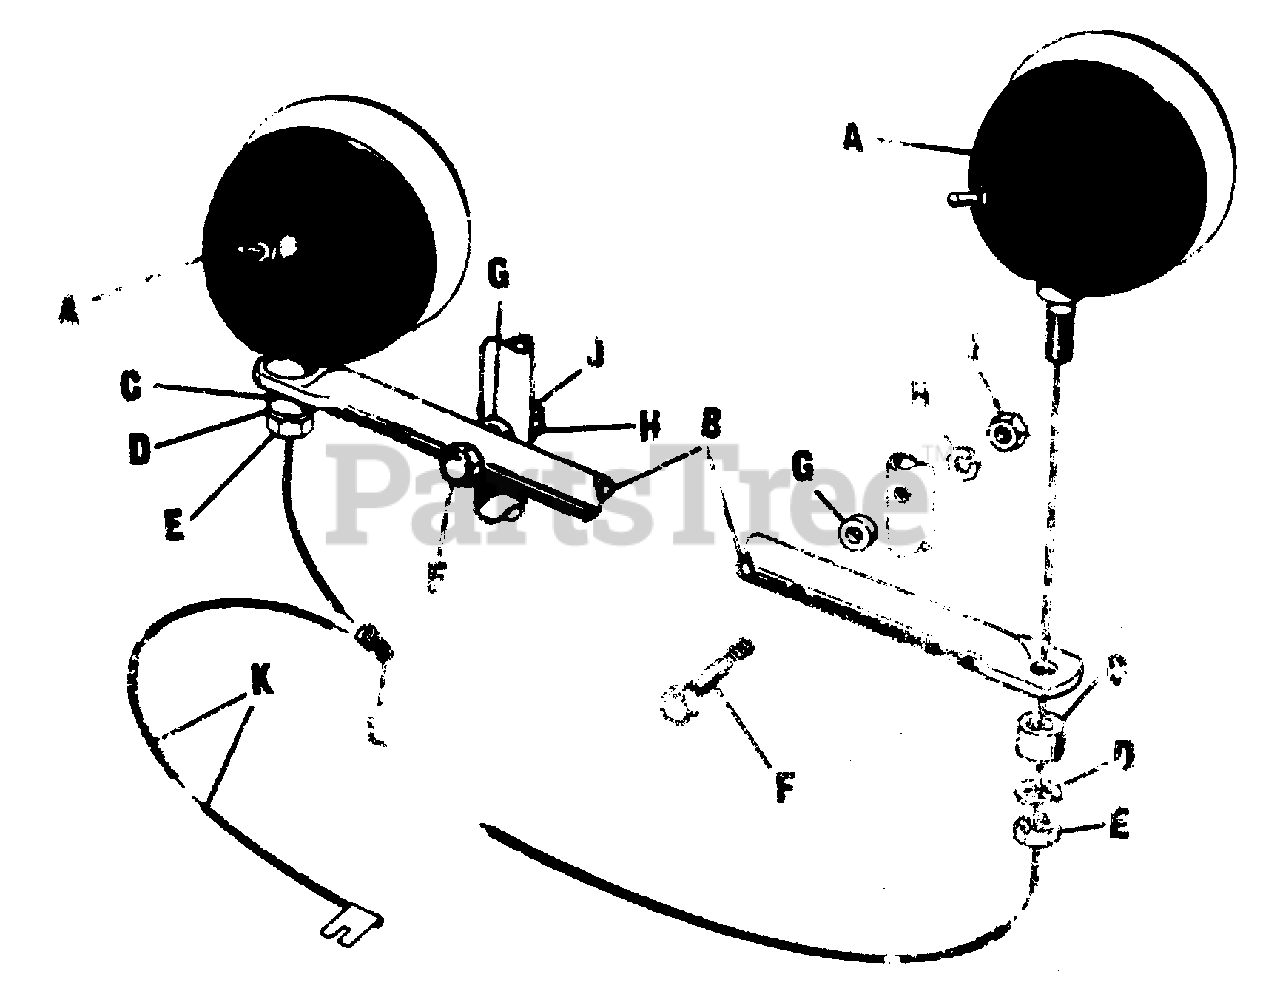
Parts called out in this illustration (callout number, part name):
A	Lamp Assembly
B	Supports, Lights
D	Lock Washer, 1/2"
E	Hex Nut Full, 1/2"-13
F	Hex Capscrew, 5/16"-18 x 2-1/2"
H	Lock Washer, 5/16"
J	Hex Nut, Full, 5/16"-18
K	Wire-Reg. to Front Lamp
L	Connector-Wire
